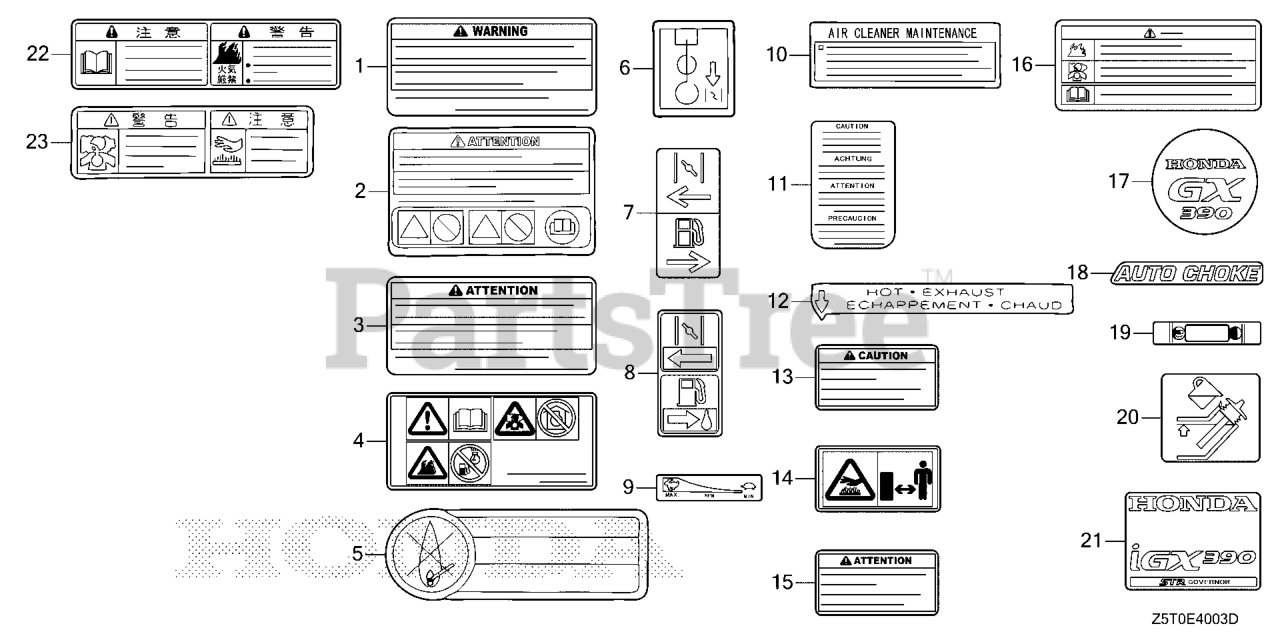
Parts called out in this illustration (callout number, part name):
3	MARK, OPERATOR CAUTION (FRENCH)(MADE IN THAI)
4	MARK, OPERATOR CAUTION (PICTOGRAPH)
14	MARK, EX. CAUTION (PICTOGRAPH)
15	MARK, EX. CAUTION (FRENCH)
